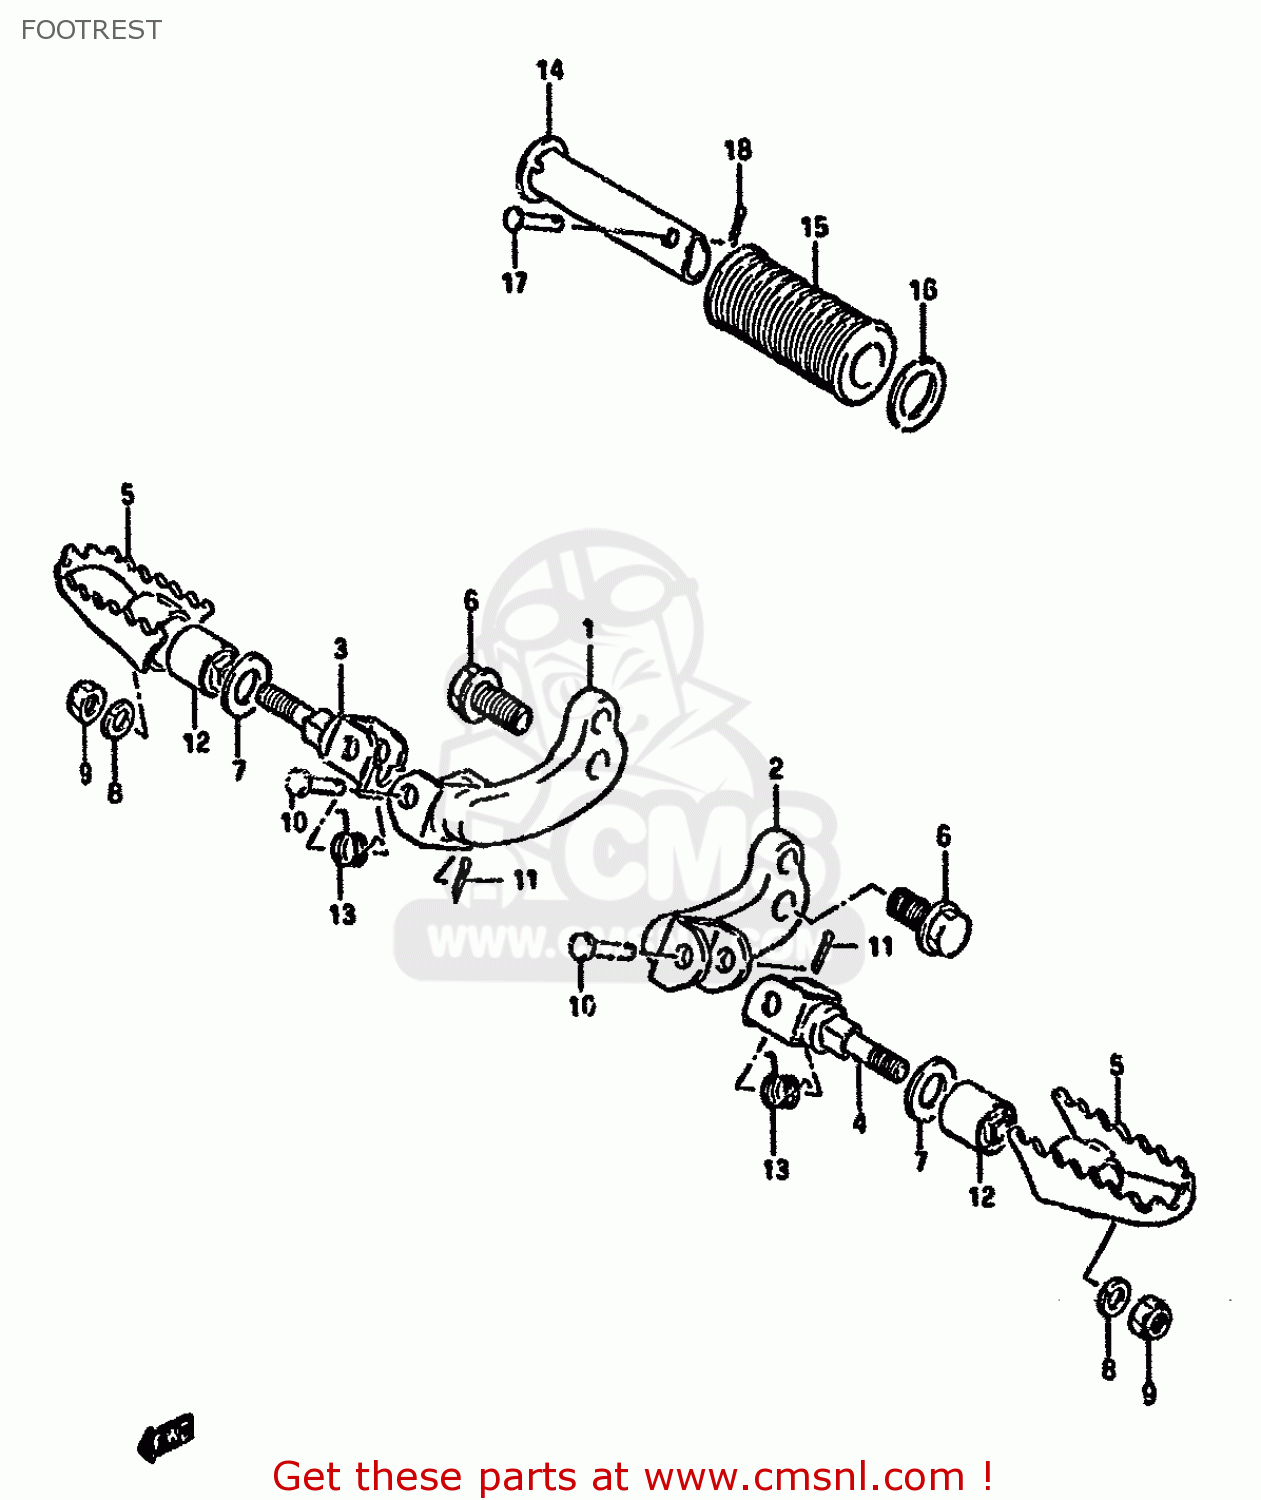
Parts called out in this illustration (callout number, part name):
1	BAR,FRONT FOOTREST
2	BAR,FRONT FOOTREST,LEFT
3	BRACKET,FRONT FOOTREST
4	HOLDER COMP,FRONT FOOT
5	FOOTREST,FR
6	BOLT
7	WASHER
8	WASHER,LOCK
9	NUT
10	PIN
11	PIN
12	BUSH
13	SPRING
14	BAR,FOOTREST RUBBER
15	RUBBER,PILLION FOOTREST
16	WASHER (19.5X32X2)
17	PIN
18	PIN 20X20
